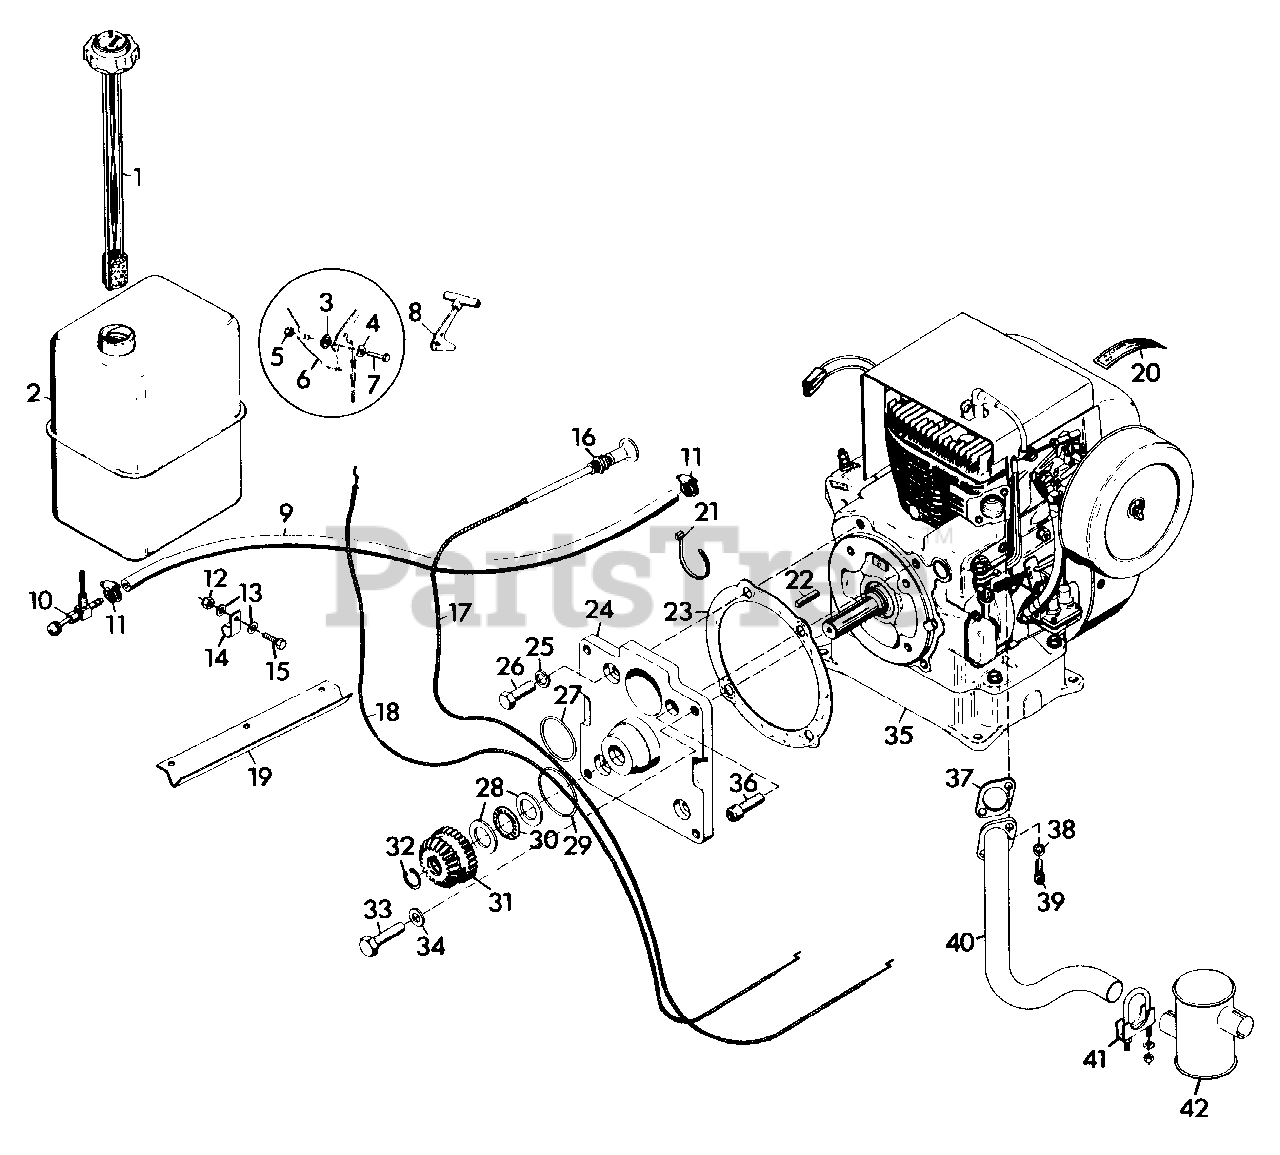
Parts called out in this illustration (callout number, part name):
1	GAUGE, GAS
2	TANK, FUEL
3	WASHER, FRICTION
4	WASHER, SPRING
5	NUT, LOCK 1/4-28
6	BRACKET, MOUNTING
7	BOLT, HEX 1/4-28X.75
8	ASSEMBLY, KNOB AND LEVER
9	LINE, FUEL
10	VALVE, FUEL 90 DEG. REVERSE FLOW
11	CLAMP, HOSE
12	NUT, LOCK 5/16-18
13	WASHER, FLAT .344X.688X.065
14	CLAMP, NYLON
15	BOLT, HEX 5/16-18X1.00
16	NUT, JAM 3/8-24
17	CONTROL, CHOKE
18	ASSEMBLY, CHOKE CONDUIT
19	SHIELD, HEAT
20	DECAL, AIR CLEANER INSTRUCTION
21	TIE, CABLE
22	KEY, SQUARE .250X1.250
23	GASKET, ADAPTOR
24	ADAPTOR, ENGINE
25	WASHER, LOCK 7/16 SP HEAVY
26	BOLT, HEX 7/16-14X1.125
27	O-RING, 2.500X2.750X.125
28	RACE, BEARING THRUST 1.125X1.750X.123/.126
29	O-RING, 3.000X3.188X.094
30	BEARING, THRUST 1.127X1.740X.078
31	GEAR, SPUR AND BEVEL, INPUT
32	RING, RETAINING 1.125 SHAFT
33	BOLT, HEX 1/2-13X1.25
34	WASHER, LOCK 1/2 REG.
35	ENGINE, 12 HP ELECTRIC 4-WHEEL
36	SCREW, CAP 7/16-14X1.0 SOCKET HEAD
37	GASKET, EXHAUST
38	WASHER, LOCK 5/16 REG.
39	SCREW, CAP 5/16-18X.75 S/HD
40	HEADER, EXHAUST
41	CLAMP, MUFFLER
42	MUFFLER, EXHAUST
NS	NUT, LOCK 10-32
NS	SCREW, MACHINE 10-32X.50 PHD
